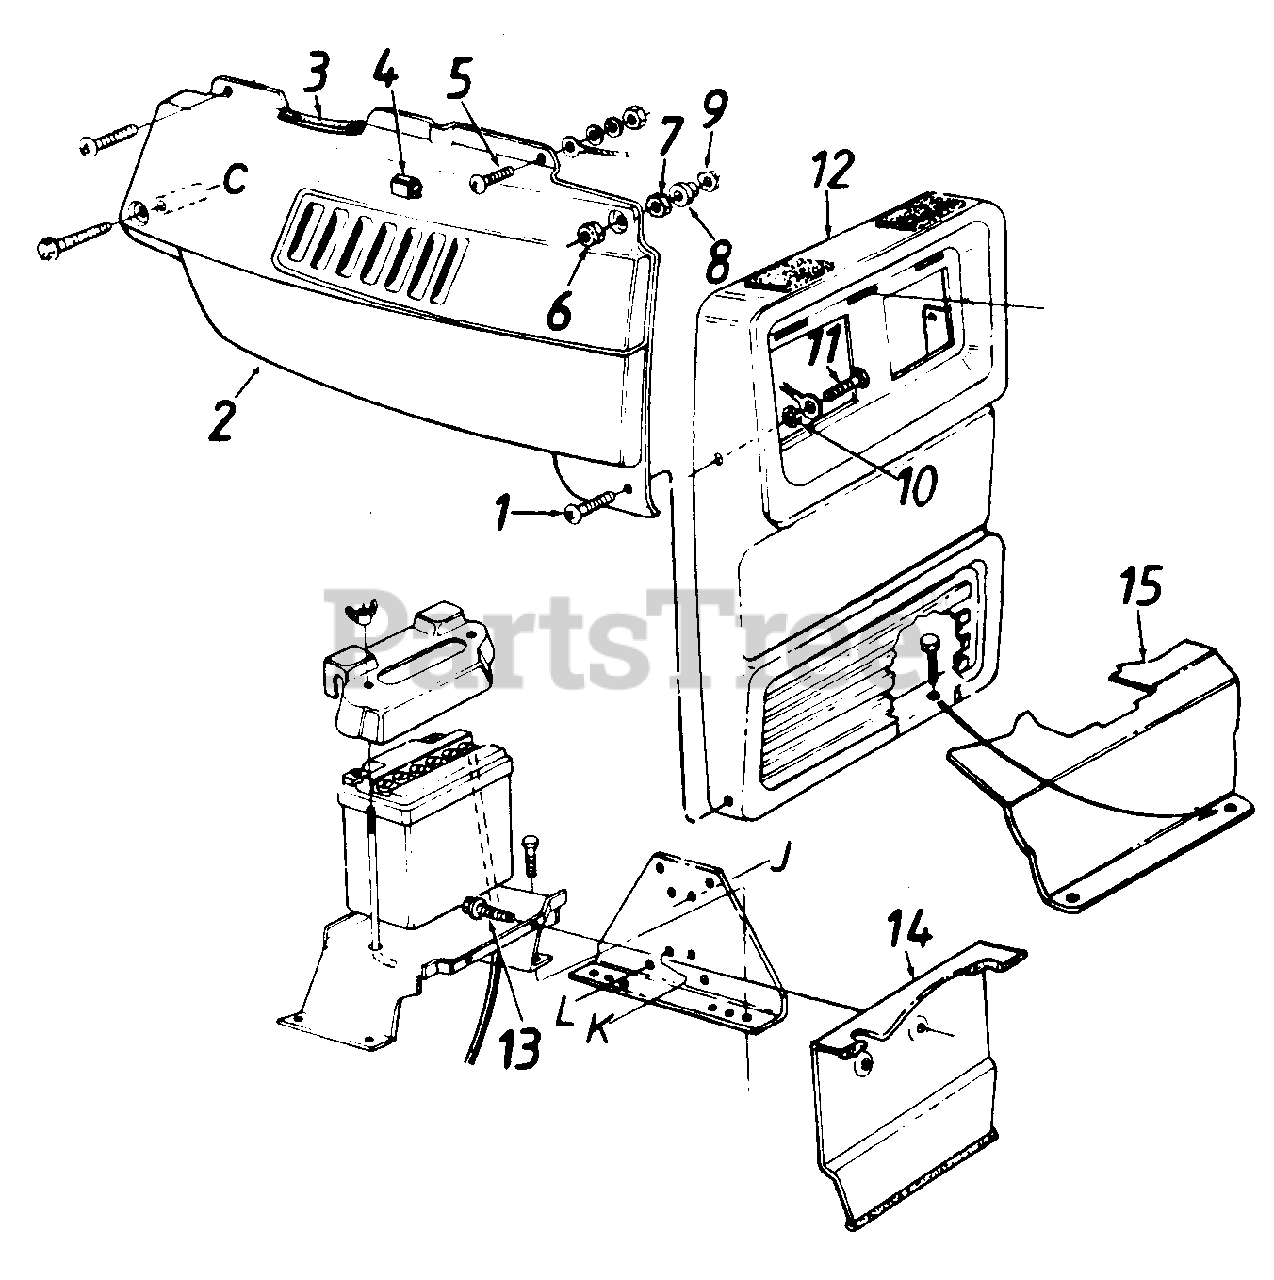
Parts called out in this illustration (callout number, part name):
1	Truss Mach. Scr. 1/4-20 x .5" Lg.
2	Side Cover-R.H.
3	Trim Strip-6"
4	Clamp
5	Truss Mach. Scr. 1/4-20 x .75" Lg.
6	Acorn Nut 1/4-20 Thd.
7	Hex Nut 1/4-20 Thd.
8	Shld. Spacer
9	Washer.39" I.D.
10	Ext. L-Wash 1/4" I.D.
11	Hex Bolt 1/4-20 x .88" Lg.
12	Grille-Used w/Headlight Bezel
13	Hex Tap Scr. 1/4-20 x .5" Lg.
14	Baffle
15	Heat Shield
